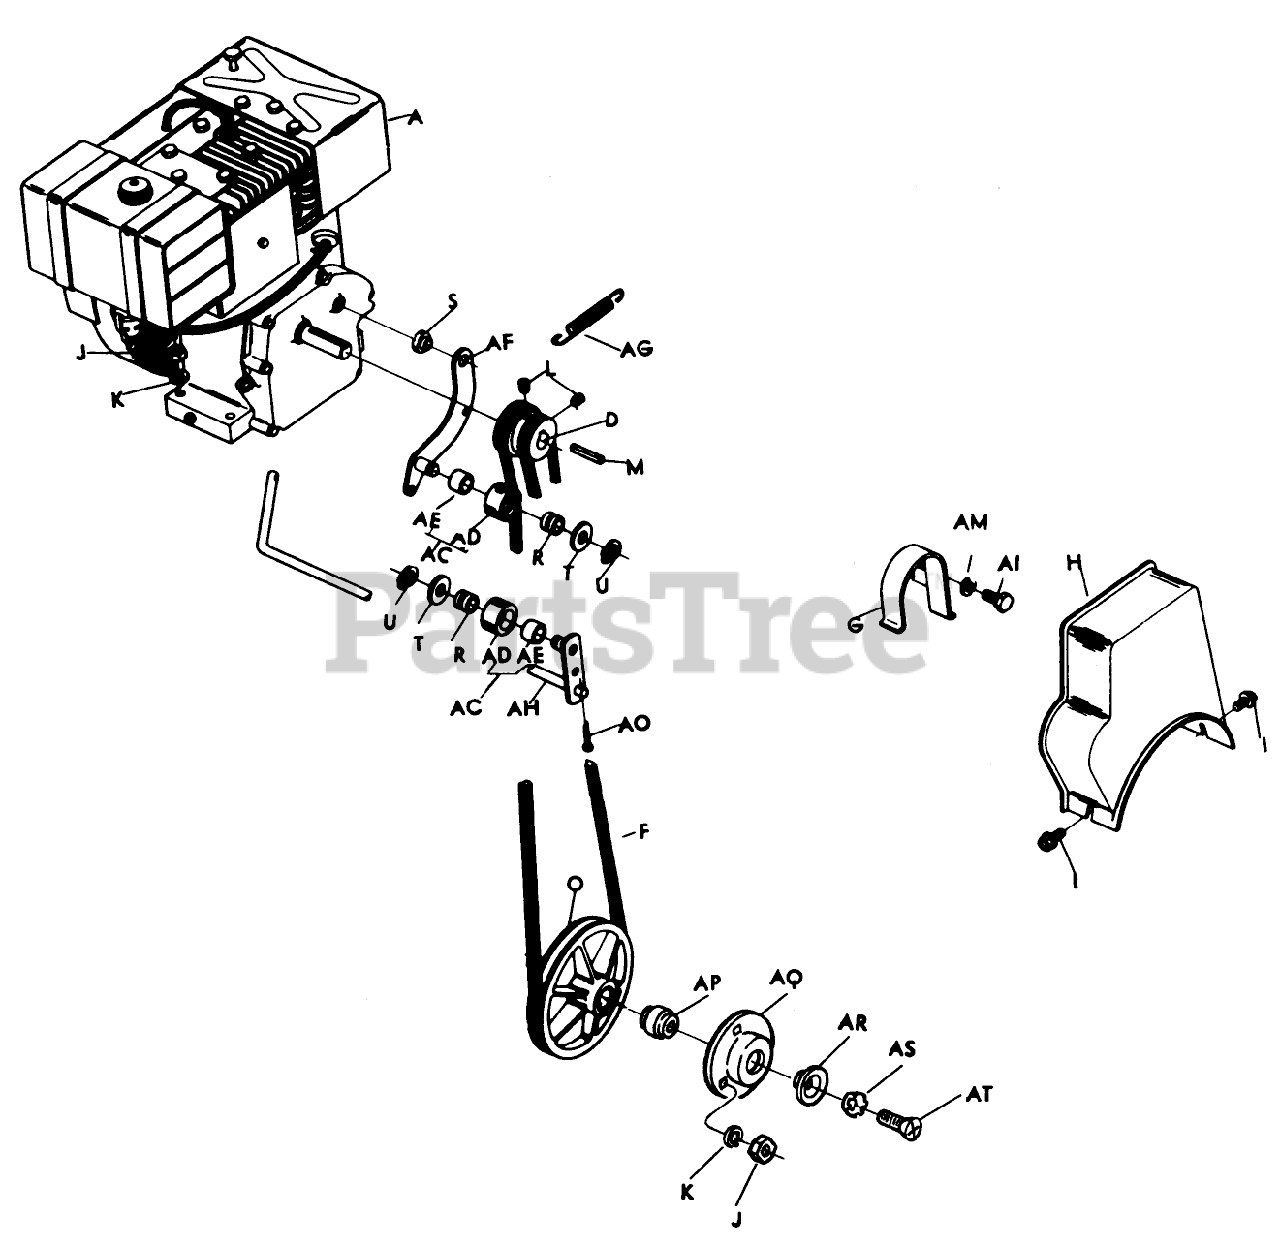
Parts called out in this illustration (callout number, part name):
A	Engine-5 H.P.-BS Model 130202-0237-02
J	5/16-18 Hex. Nut, Pl.
K	5/16 Lock Washer, Pl.
L	5/16-18 x 5/16 Set Screw, H.T.
M	Sq. Key, 1/4 x 1/4 x 1 3/4, 8 HP. Units Sq. Key, 3/16 x 3/16 x 2, 5 HP. Units
AI	1/2-20 x 1 1/4 Hex. Hd. Cap Screw, Pl.
AM	1/2 Lock Washer, Pl.
AO	1/8 x 3/4 Cotter Pin, Pl.
AS	3/8 Countersunk Lock Washer, Pl.
AT	3/8-16 x 1 Fl. Hd. Phillips Mach. Screw, Pl.
